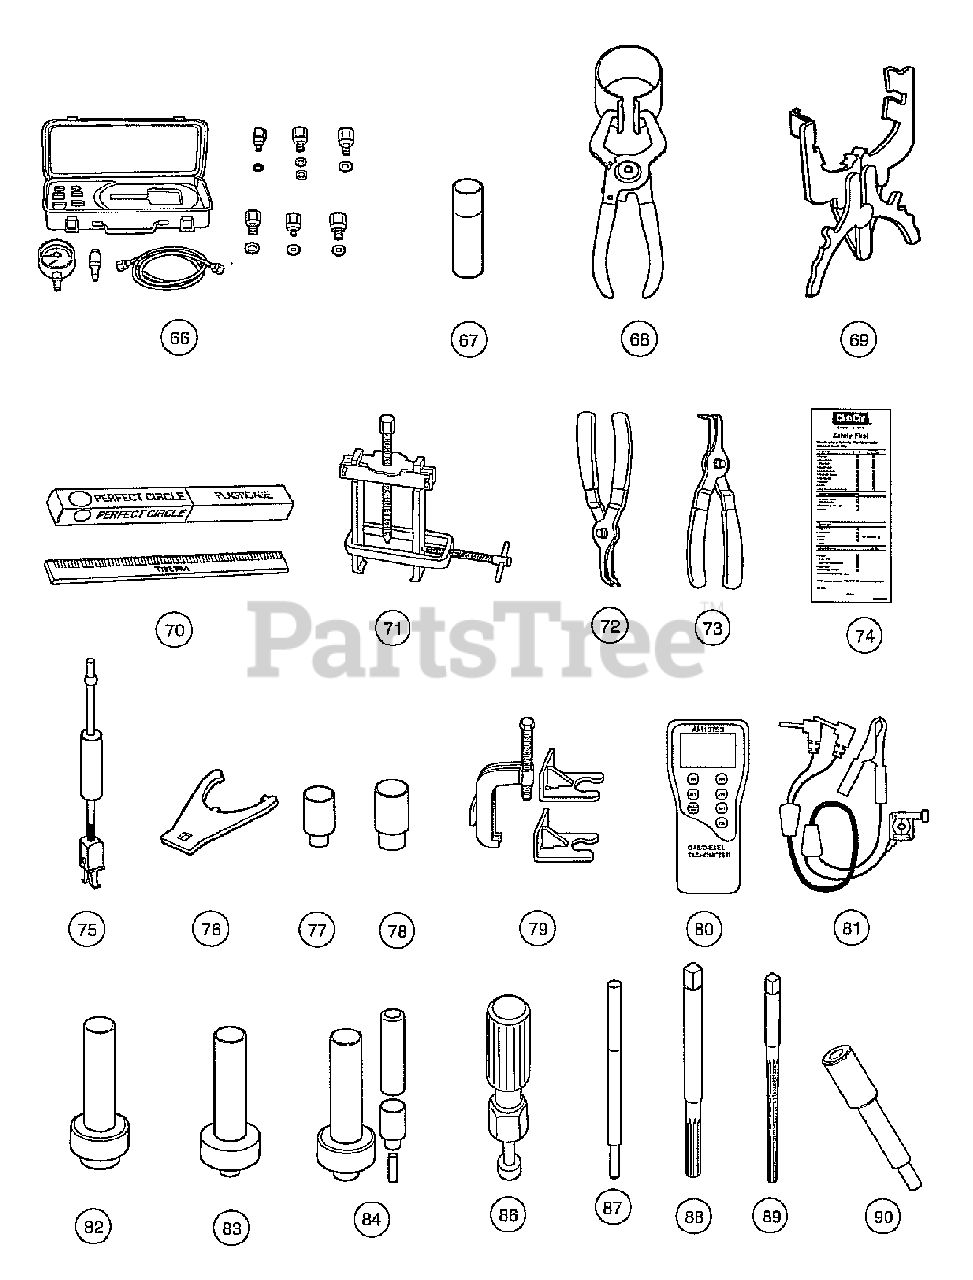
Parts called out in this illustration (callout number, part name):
66	Oil Pressure Tester
67	Paint, Touch-Up - Beige
67	Paint, Touch-Up - Black
67	Paint, Touch-Up - Burgundy
67	Paint, Touch-Up - Classic Blue (Navy)
67	Paint, Touch-Up - Dark Gray
67	Paint, Touch-Up - Dark Green
67	Paint, Touch-Up - Gray
67	Paint, Touch-Up - Red
67	Paint, Touch-Up - Royal Blue (Pacific Blue)
67	Paint, Touch-Up - White
68	Piston Ring Compressor Kit (FE290, FE350 and FE400 engines)
69	Piston Ring Pliers
70	Plastigage
71	Puller, Special Use
72	Retaining Ring Pliers, 45° External
73	Retaining Ring Pliers, 90° Internal
74	Safety First Card (50 per pack)
75	Seal Puller
76	Spanner Wrench
77	Steering Column Bearing Press Tool
78	Steering Column Retaining Ring Tool
79	Steering Wheel Puller Tool
80	Tachometer
81	Tachometer Diesel Probe
82	Transaxle Axle Seal Tool
83	Transaxle Pinion Seal Tool
84	Transmission Tool Kit
86	Valve Clearance Adjuster Screw Holder
87	Valve Guide Driver
88	Valve Guide Reamer (FE290, FE350, and FE400 only)
89	Valve Guide Reamer, 6.6 mm
90	Valve Guide Replacement Tool
